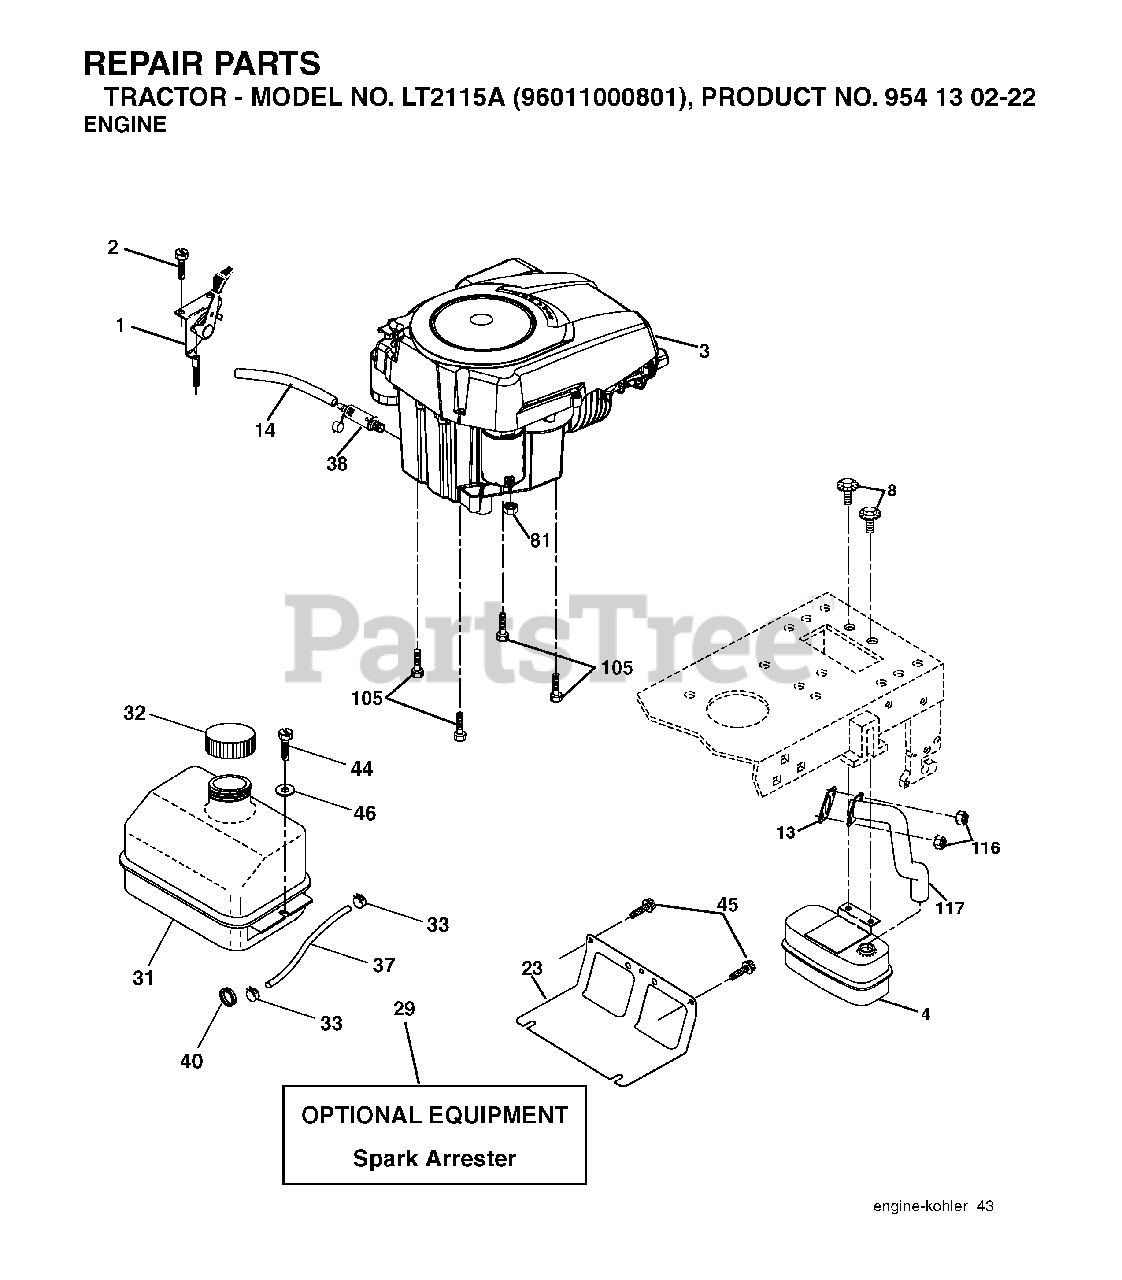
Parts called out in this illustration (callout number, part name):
1	CONTROL.THROTTLE.LT/YT
2	SCREW
4	MUFFLER.SINGLE.CYL.KOHL/B&S
8	BOLT, 5/16-18 X 1 3/4
13	GASKET ENGINE
14	TUBE, DRAIN OIL ASM.
23	SHEILD.BROWNING.DBR.GUARD
29	ARRESTER SPARK (OPTIONAL)
31	FUEL TANK
32	FUEL CAP
33	HOSE CLAMP
37	LINE.FUEL.20
38	PLUG DRAIN OIL EASY
40	GROMMET T
44	SCREW HEXWSHR 1/4-20X3/4
45	SCREW, 3/8-16X3/4
81	NUT
105	SCREW 3/8-16X1
116	NUT.HEX.FLANGE.TOPLOCK
117	TUBE EXHAUST
